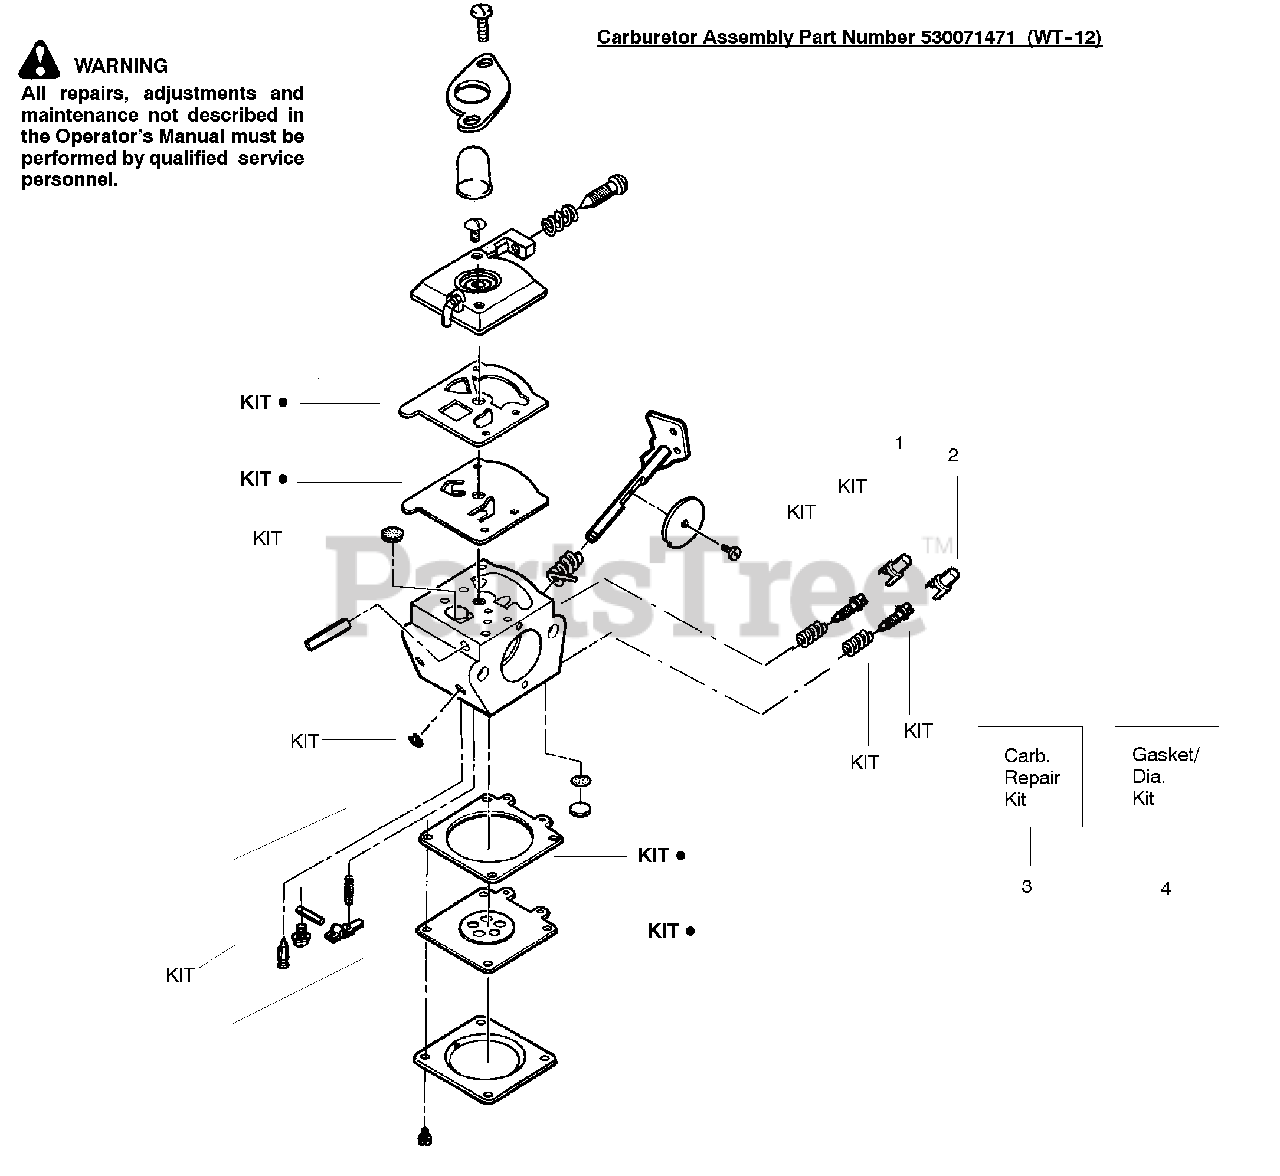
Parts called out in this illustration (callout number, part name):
1	Limiter Cap-Low (tan)
2	Limiter Cap-High (brown)
3	Carburetor Repair Kit
4	Gasket/Diaphragm Kit
